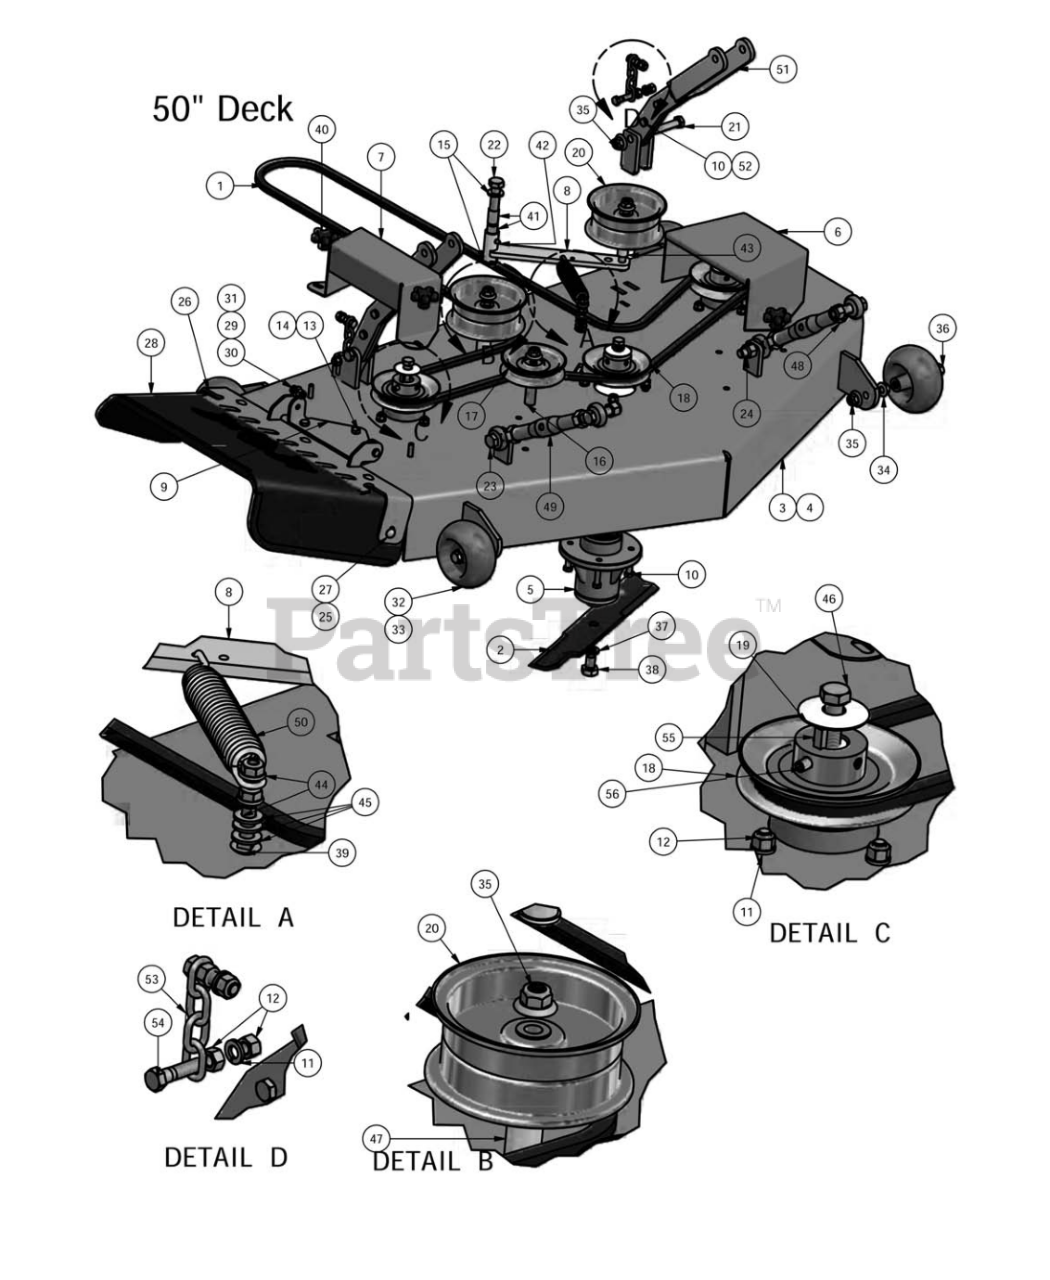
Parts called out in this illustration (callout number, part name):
1	50" Deck Belt
2	50" Fusion Blade
3	50" Deck
4	50" Deck Complete
5	Spindle
6	Spindle Cover
7	Spindle Cover (Smaller)
8	Deck Idler Arm
9	Discharge Chute Hanger (deck mounted)
10	3/8" x 1 1/4" Hex Bolt
11	3/8" Lock Washer
12	3/8" Hex Nut
13	3/8" x 3/4" Hex Bolt
14	3/8" Flange Nut
15	.635 ID Plastic Washer
16	Pup Pulley Spacer
17	4 3/4" Idler Pulley
18	5" Deck Pulley
19	Cup Washer
20	5 3/4" Deck Idler Pulley
21	1/2" x 2 1/2" Hex Bolt
22	5/8" x 4" Hex Bolt
23	5/8" x 2 1/2" Hex Bolt
24	5/8" Nylock Nut
25	5/16" Flange Nut
26	60" Upper Hanger Plate
27	5/16" x 1 1/4" Carriage Bolt
28	Rubber Discharge Chute
29	.360 ID Plastic Washer
30	5/16" x 1" Hex Bolt
31	3/8 Nylock Nut
32	Anti-Scalp Rollers
33	Deck Wheel Assembly
34	1/2" Flange Nut
35	1/2-13 Nylon Flange Nut-Orange
36	1/2" x 4" Bolt (Grade 8)
37	5/8" Lock Washer
38	Heavy Hex Bolt
39	3/8" x 1 1/4" Carriage Bolt
40	5/16" Knob
41	5/8" x 1 1/8" Brass Bushing
42	1/4" Drive in Grease Fitting
43	1 1/4" Pulley Spacer
44	3/8" Nylock Flange Nut
45	3/8" Flat Washer
46	1/2"-20 x 1 1/2- Grade 5 Fine Thread Bolt
47	1 3/4" Pulley Spacer
48	3/4" Left Handed Nut
49	Turnbuckle
50	Deck Idler Spring
51	Deck Support Arm
52	3/8" Hex Nut
53	ZT Deck Hanger Chain Assembly
54	3/8" x 1 1/2" Hex Bolt
55	1/4" x 1" Key
56	Set Screw
